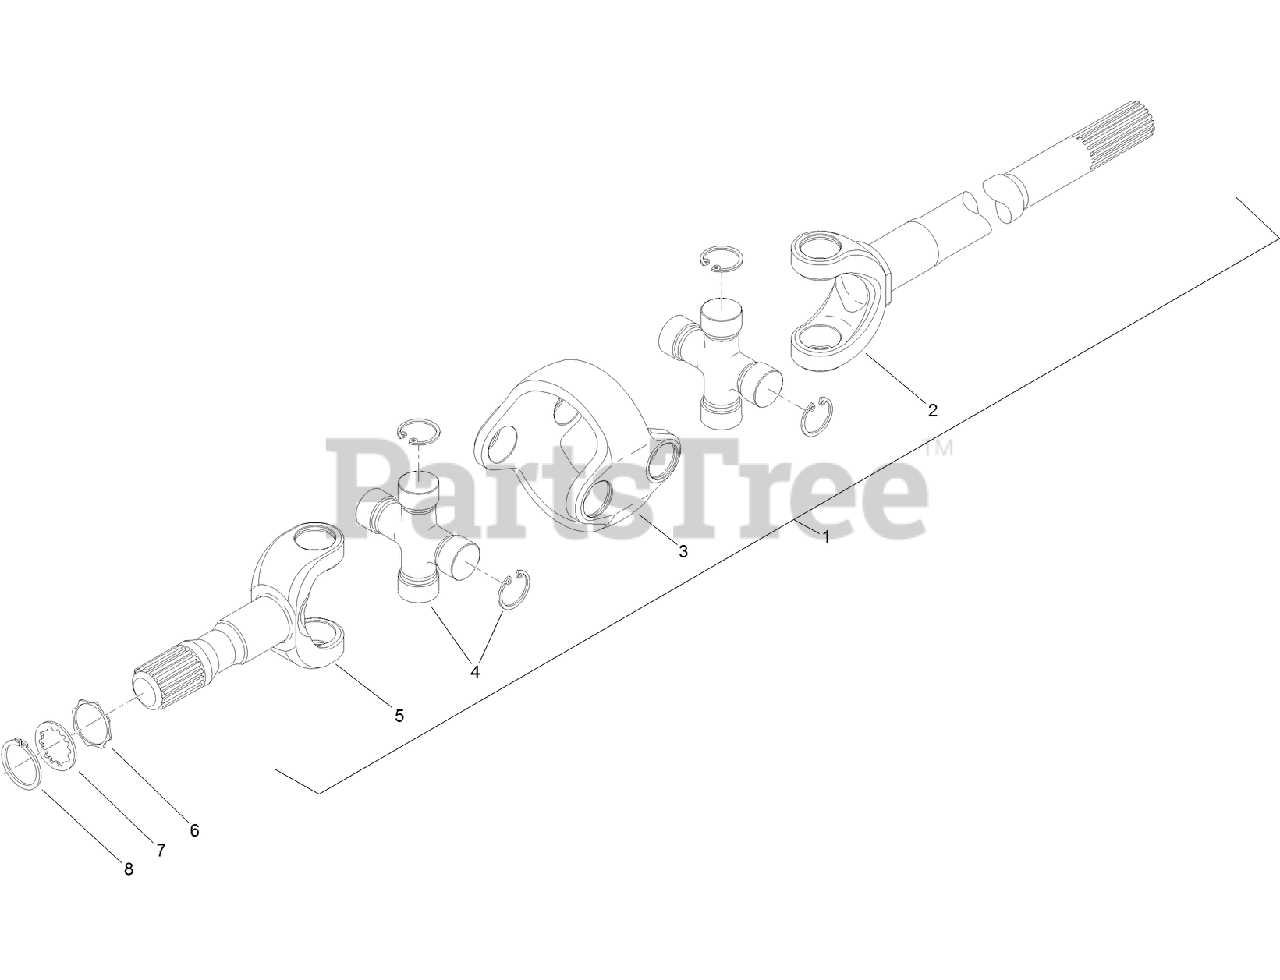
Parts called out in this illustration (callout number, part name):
1	DOUBLE JOINT ASM
2	FORK (DIFFERENTIAL SIDE)
3	BODY-CENTRAL
4	Spider
5	FORK (WHEEL SIDE)
6	WASHER-THRUST
7	WASHER
8	RING-SNAP
